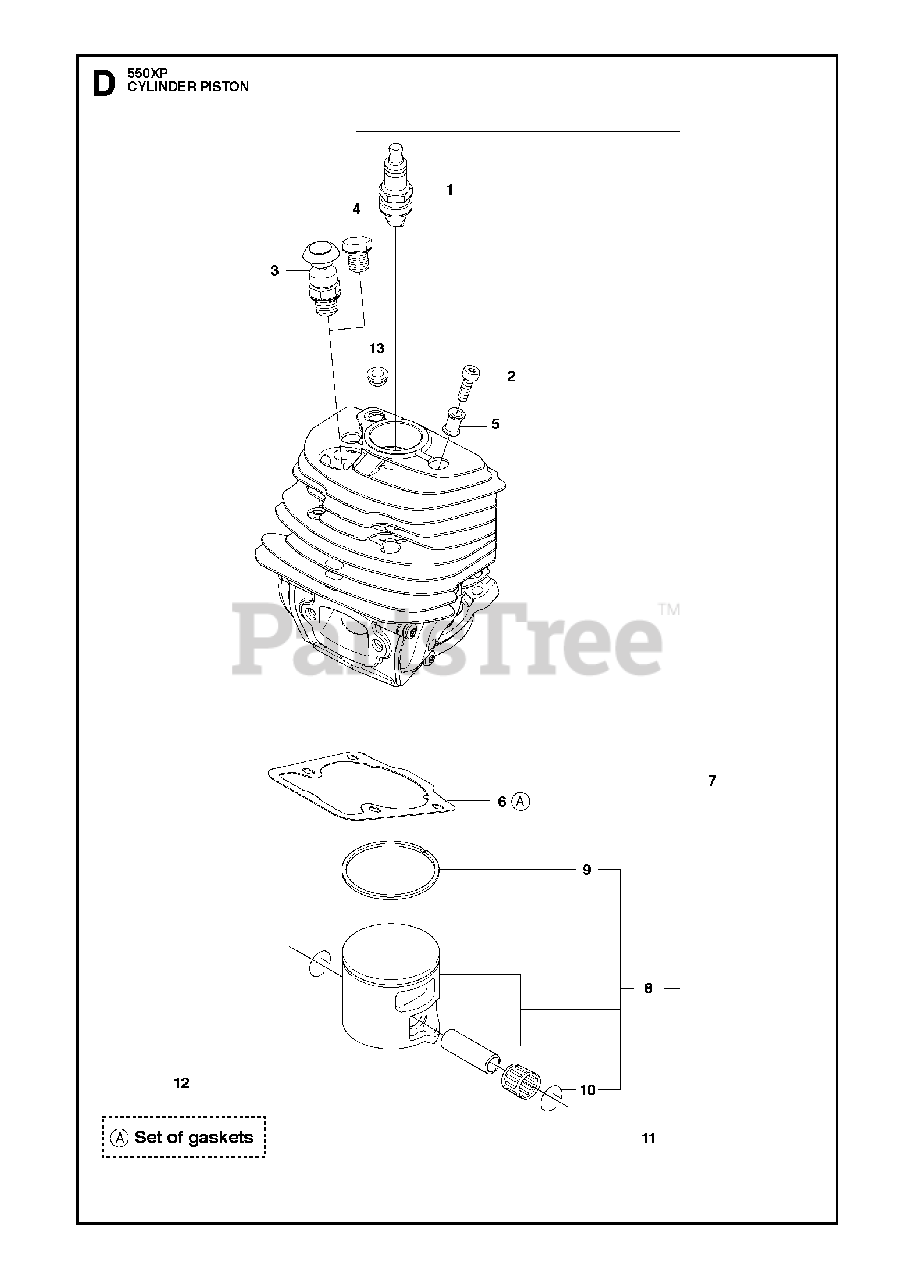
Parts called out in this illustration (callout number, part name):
1	CMR6H SPARK PLUG NGK
2	SCREW MC6S 5X40
3	DECOMPRESSION VALVE
4	CYLINDER PLUG
6	GASKET
7	CYLINDER-PISTON ASSY
8	PISTON ASSY
9	PISTON RING
10	LOCKING RING
11	SUPPORT BUSHING
12	GASKET KIT 50CC
13	BUSHING
